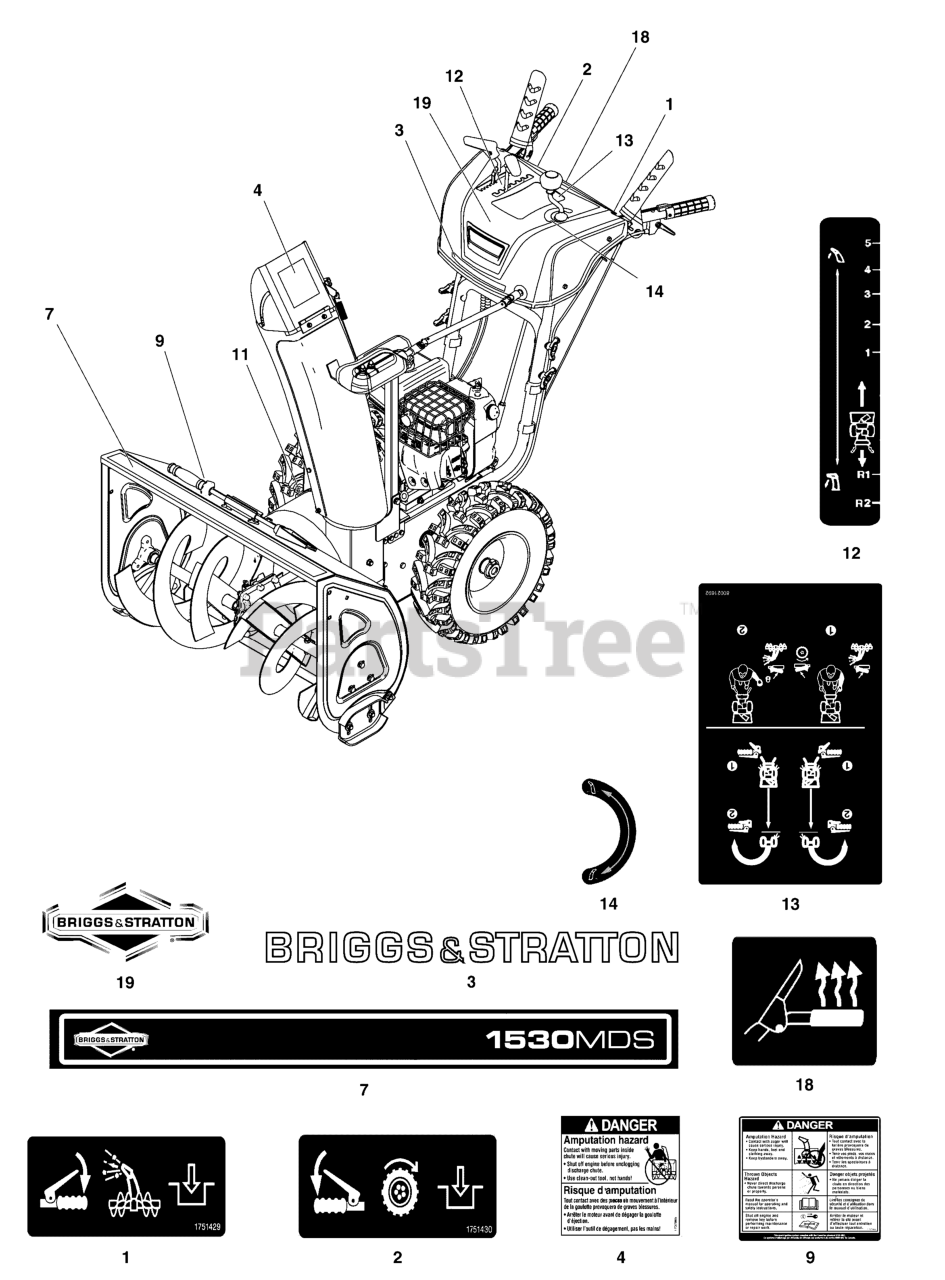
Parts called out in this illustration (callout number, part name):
1	DECAL, Auger Control
2	DECAL, Traction Control
3	DECAL, Briggs & Stratton Wordmark
4	DECAL, Danger Chute Warning, FR/ENG
7	DECAL, Model 1530MDS
9	DECAL, Danger Foot, FR/ENG
11	DECAL, I.D. Plate
12	DECAL, 1-6 Transmission Speed Control
13	DECAL, Free Hand Operation
14	DECAL, Chute Rotation
18	DECAL, Heated Hand Grip Switch
19	DECAL, Briggs & Stratton Logo
